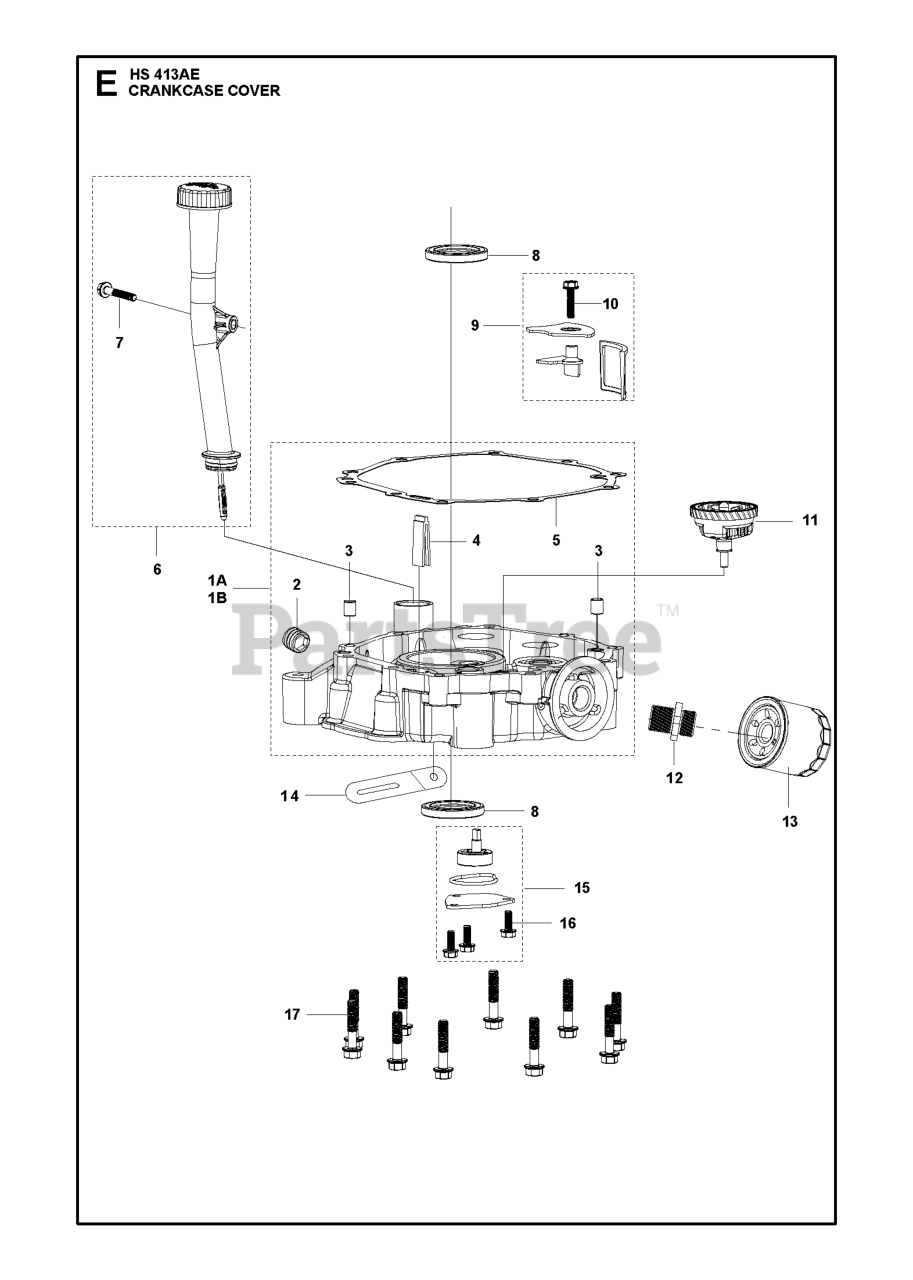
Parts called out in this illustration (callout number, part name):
1	TRANSMISSION.ASM.17
2	GEARCASE.ASM.DRT.LH.
2	OIL PLUG OIL PLUG
3	GASKET
3	PIN LOCATION PIN
4	NEEDLE BRNG LT
4	BLOCK OIL RETURN BLOCK
5	THRUST WASHER
5	GASKET CRANKCASE COVER GASKET
6	GEAR.PINION.INPUT.DRT
6	SERVICE KIT KIT.FILL.TUBE (KIT
7	SHAFT.INPUT.D.9TEETH
7	BOLT GB/T 5789: M6 L=35
8	SEAL OIL SEAL
9	WASHER, SEAL (2 2)
9	STRAINER OIL STRAINER
10	BALL, STEEL
10	BOLT GB/T 5789: M6 L=25
11	SPRING-SHIFT CRT
11	SERVICE KIT KIT.COMPONENTS OF
12	OIL PLUG OIL FILTER MOUNTING P
13	BRACKET ASM.SHIFT.CRT
13	FILTER OIL FILTER (ENG.452)
14	SHIFT FORK TI
15	OIL PUMP ASSY OIL PUMP ASSY
16	SHAFT.SHIFT.DRT
17	BOLT T370: M8 L=40 S=12
20	GEAR ASSY CRT
21	GEAR-REV IDLR CRT
22	NEEDLE BEARING TI
23	SHAFT.IDLER.REVERSE.CRT
24	LOCKWASHER
25	NUT.ASF.HEX.7/16
27	BEARING, SHAFT, GROUNDDRIVE LH
30	GROUND SHAFT ASS'Y
31	BEARING, SHAFT RH CRT
33	SPRCKT 8 GEAR CRT
34	SHAFT.SECONDARY.REDUCTION.CRT
35	SCRW WHIZ LOK CRT
36	GEAR & SPROCKET.ASM.WBEARIN
37	BEARING.NEEDLE.CRT
38	ASM.GEAR & SPROCKET
39	GEAR.CLUSTER.DRT.TILLER
41	SHAFT.REDUCTION.FIRST.DRT
42	BRNG RACE T
44	SEAL ASM, OIL
48	GEARCASE.ASM.DRT.RH.
49	TINE SHAFT
50	CHAIN.TILLER
51	SCREW
52	NUT
53	KIT.BEARING.TILLER.
54	GEAR.ASM.DRT.TILLER
55	BEARING.NEEDLE
56	GEAR.DRT.IDLER
57	SPACER.SPLIT
58	BOLT SHOULDER 1/4-20 UNC X.875
60	FITTING.GREASE.TAPERED
